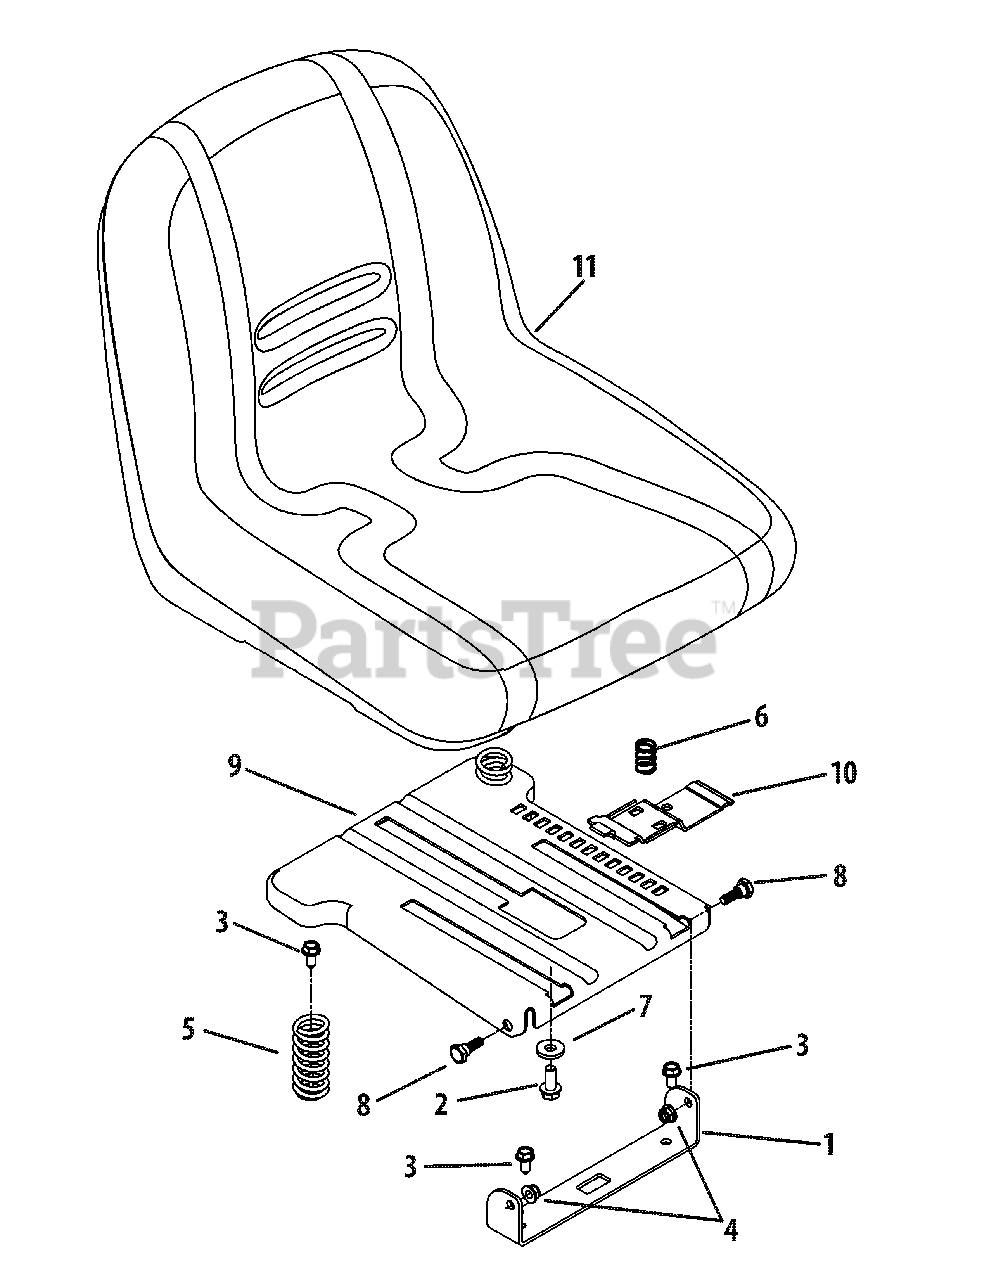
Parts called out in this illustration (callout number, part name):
2	Hex Flange Bolt, 3/8-16 x .875
3	Hex Washer Screw, 5/16-18 x .750
4	Flange Lock Nut, 5/16-18
5	Compression Spring
6	Compression Spring
7	Flat Washer, .385 x 1.0 x .135
8	Shoulder Screw, 5/16-18 x .437 x .268
9	Seat Mount Bracket
10	Seat Adjustment Lever
11	High Back Seat
